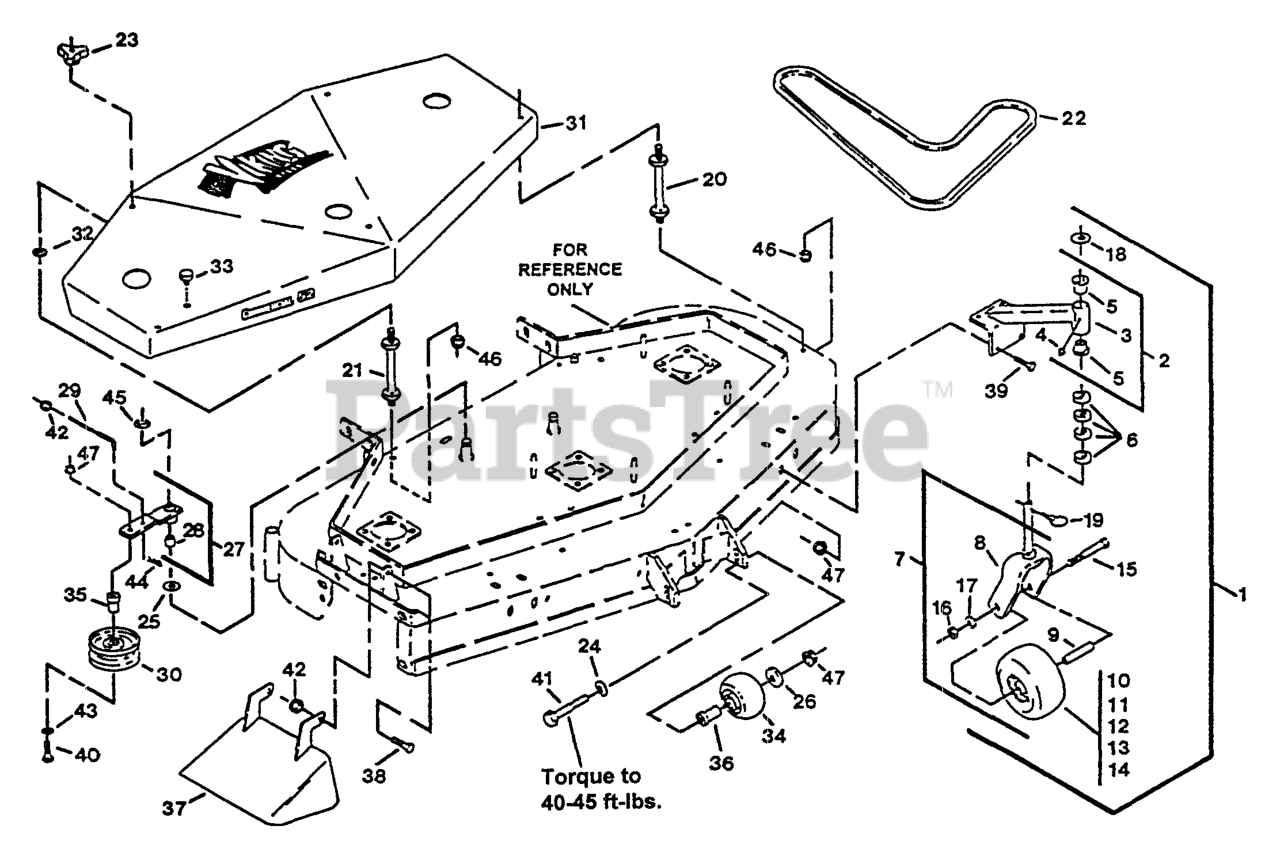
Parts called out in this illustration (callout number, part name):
1	CASTER/MOUNT ASM
2	SUPPORT ASM
5	BEARING-FLANGED
6	SPACER-CASTER
13	BEARING
14	BUSHING
18	WASHER-FLAT
20	STUD-SHIELD, BELT (SHORT)
21	STUD-SHIELD, BELT (LONG)
22	BELT,BLADE DRIVE 48
23	KNOB-3 PRONG
25	WASHER-SPINDLE
27	ARM WLDMNT W/BUSHING
28	BEARING,POWDERED METAL
29	LINKAGE
30	IDLER,PULLEY
31	BELT SHIELD ASSY 52METR
34	ROLLER-SCALP, ANTI
35	BUSHING-IDLER
36	BUSHING-ROLLER
37	WLD,CHUTE DISCHARGE
44	PIN-COTTER
